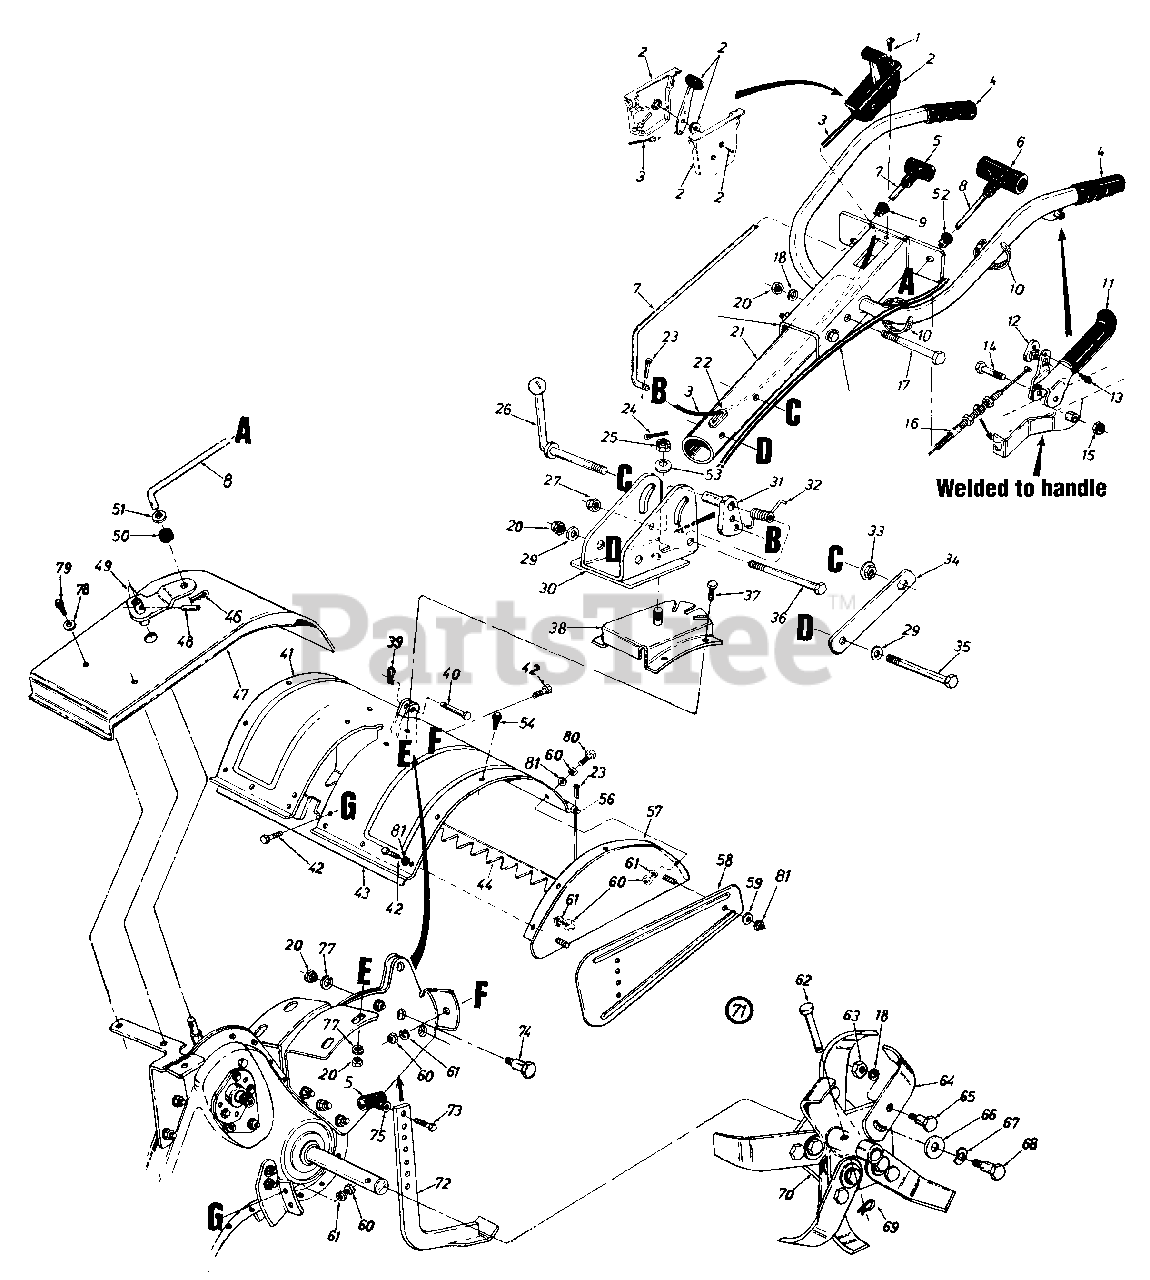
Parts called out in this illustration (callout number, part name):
1	Truss Mach. AB-Tap. Scr. #10 x .5" Lg.
2	Throttle Control Box Ass'y.
3	Throttle Control Wire
4	Handle Grip
5	Small "T" Knob
6	Large "T" Knob
7	Clutch Rod
8	Control Rod 37" Lg.
9	Snap On Bushing 3/8" Dia.
10	Cable Tie-Self Clinching
12	Barrel Cable Hold Down
13	Hex B-Tap Scr. #10 x .44" Lg.
14	Hex Bolt 3/8-24 x 2.25" Lg.
15	Hex Jam L-Nut 3/8-24 Thd.
16	Clutch Control Cable 46" Lg.
17	Hex Bolt 3/8-16 x 3.00" Lg.
18	L-Wash. 3/8" I.D.--H.D.
23	Cotter Pin 3/32" Dia. x .75" Lg.
24	Cotter Pin 3/32" Dia. x 1.25" Lg.
25	Hex Slotted Nut 5/8-18 Thd.
26	Handle Adj. Crank
27	Hex Cent. L-Nut 3/8-16 Thd.
29	Bell-Wash. .4" 1 .D. x .87" O.D.
32	Spring Handle Adj. (Torsion)
33	Hex Flange Nut 3/8-24 Thd.
34	Bracket Hex Nut Retainer
35	Hex Bolt 3/8-16 x 3.25" Lg.
36	Hex Bolt 3/8-16 x 3.00" Lg.--Gr. 8
37	Hex Bolt 3/8-16 x 1" Lg.
40	Clevis Pin .375" Dia.
43	Bracket Reinforcement--18"
46	Intern. Cotter Pin 5/16" Dia.
49	Shifting Crank Ass'y.
50	Rubber Washer.33" I.D.
51	Fl-Wash. .4" I.D. x 1.25" O.D.
52	Snap On Bushing 1/2" Dia.
53	Bell-Wash. .63" I.D. x 1.25"
54	Hex Wash. Tap Scr.
56	Tiller Flap Rod
60	Hex Nut 5/16-18 Thd.
61	L-Wash. 5/16" I.D.
62	Clevis Pin .375" Dia.
63	Hex Nut 3/8-24 Thd.
65	Shld. Bolt 1/2" Dia. x .175
66	Fl-Wash. .51" I.D. x 1.50"
67	Bell-Wash. .515" I.D. x 1.14"
68	Shld. Bolt 1/2" Dia. x .320
69	Intern. Cotter Pin
73	Hex Bolt 3/8-16 x .75" Lg.
74	Shld. Bolt 1/2" I.D. x .62" Lg.
75	Fl-Wash. 3/8" I.D. x 5/8" O.D.
77	L-Wash. 3/8" I.D.
78	Fl-Wash. .281" I.D. x .62"
79	Hex Wash. Self-Tap Scr. 1/4-20 x .50" Lg.
80	Hex Bolt 5/16-18 x 1 1/4" Lg.
81	Cap L-Nut 5/16-18 Thd.
14979-0498	Rear Tine Shield - OLD CUB YELLOW (0498)
14979-0606	REAR TINE SHIELD - MAJESTIC ORANGE (0606)
14979-0662	REAR TINE SHIELD - OYSTER GRAY (0662)
15390-0637	SHIELD-SIDE (POWDER BLACK) - POWDER BLACK (0637)
